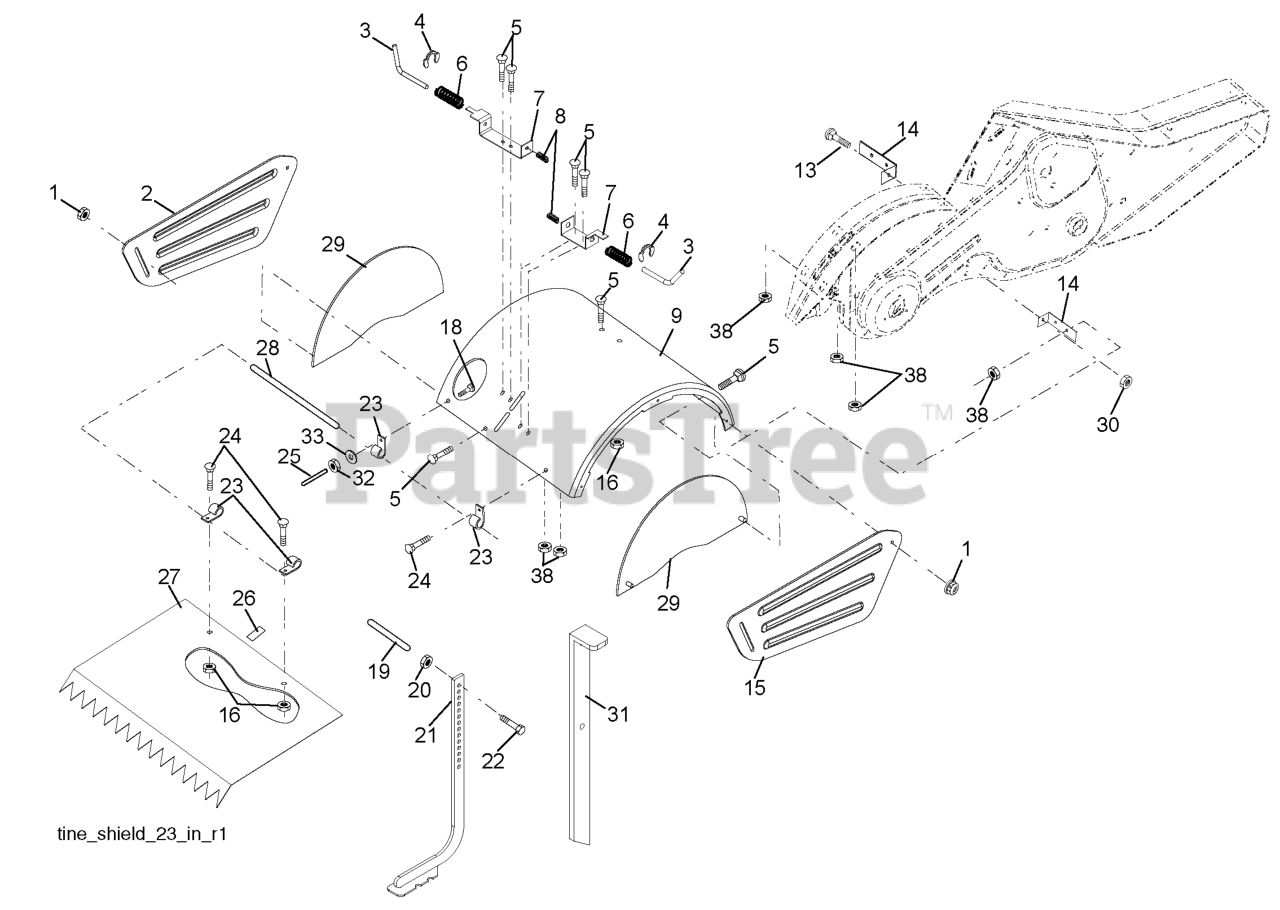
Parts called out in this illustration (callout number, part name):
1	NUT LOCK HEX FLANGE 5/16-18
2	SHIELD
3	STAKE PIN TI
4	RING, KLIP
5	BOLT, RDHD SQNK 5/16-18 X 3/4
7	BRACKET.LATCH.STAKE.3.20.BLACK
8	SPRING CRT
9	SHIELD.PNT.TINE.17"M
13	BOLT.CARRIAGE.5/16-18
14	BRACKET.TINE.SHIELD.TILLER
15	SIDE SHIELD RH
16	NUT T
20	NUT.HEX.3/8-16UNC
21	STAKE.DEPTH.16.CRT.BLACK
22	BOLT.375-16
24	BOLT
26	PAD IDLER TI
27	SHIELD LEVELING
28	PIN.HINGE.TILLER
29	SHIELD.ASM.SIDE.ORANGE.(OLD)
30	LOCKNUT-FLANGE 5/16-18
31	STAKE, DRAG
32	NUT
33	LOCKWASHER
38	NUT
